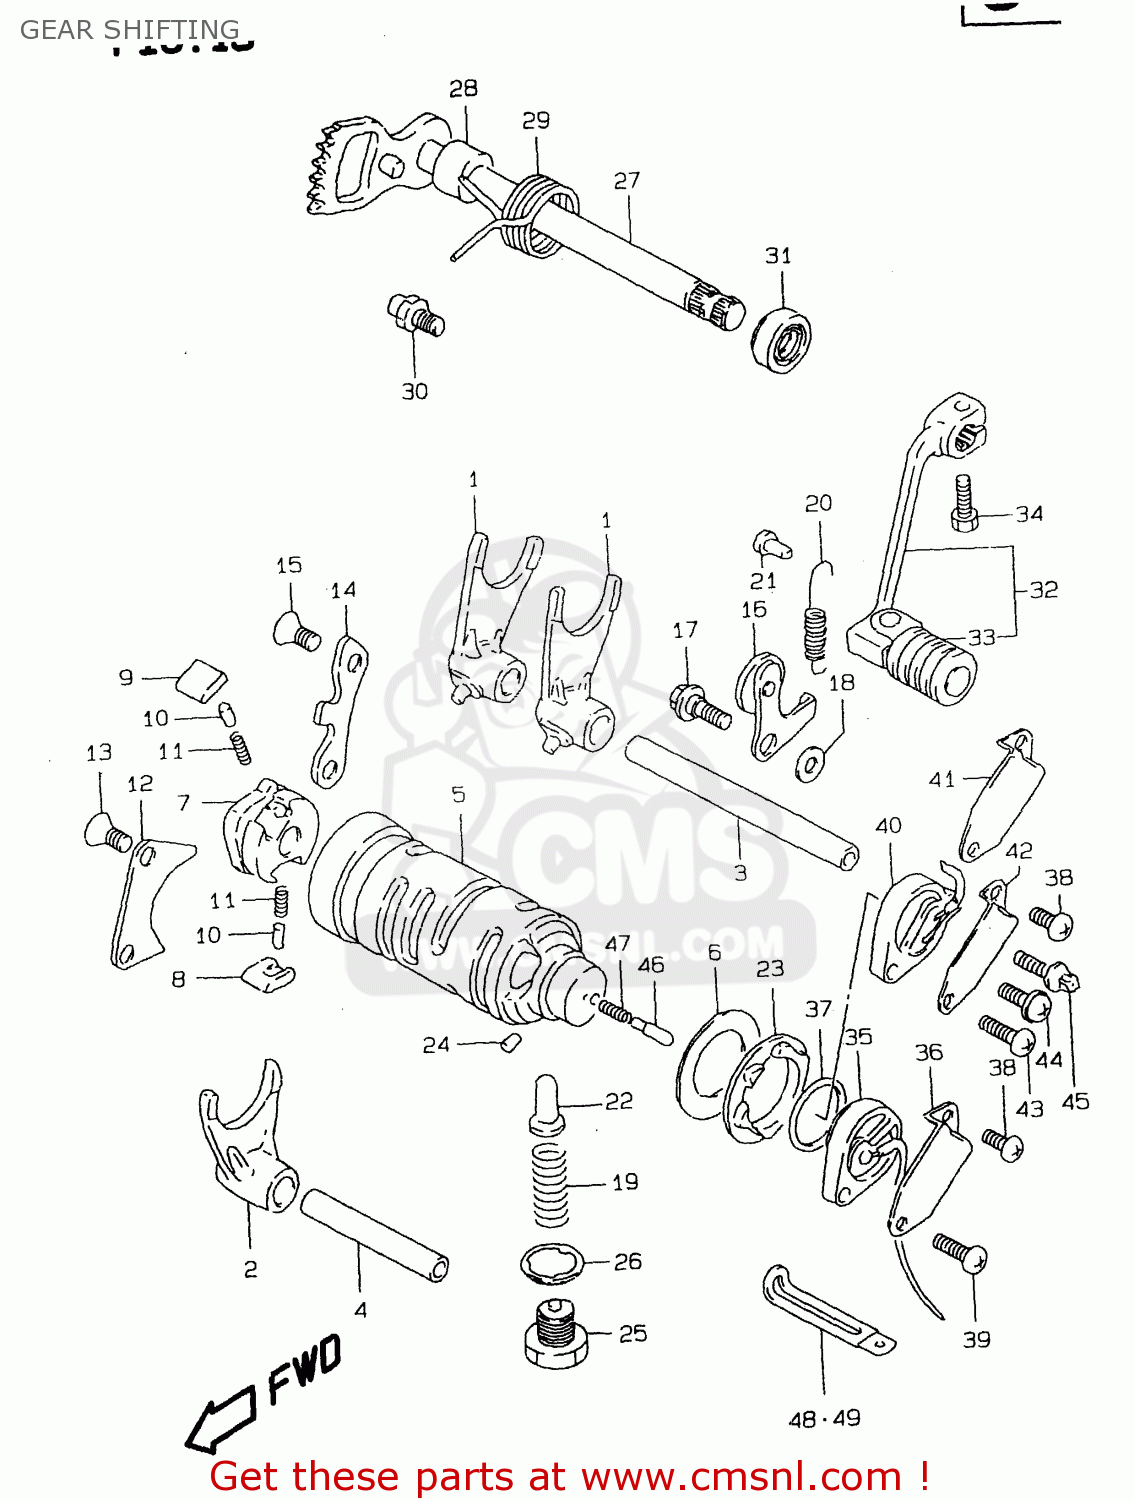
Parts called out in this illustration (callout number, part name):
1	FORK,GEAR SHIFT NO.2
2	FORK,GEAR SHIFT NO.3
3	SHAFT,GEAR SHIFT FORK(L:109)
4	SHAFT,GEAR SHIFT FORK
5	CAM,GEAR SHIFT
6	WASHER,THRUST
7	GEAR,GEARSHIFT CAM DRIVE
8	PAWL,GEAR SHIFT NO.1
9	PAWL,GEAR SHIFT NO.2
10	PIN(5X8)
11	SPRING
12	LIFTER,GEAR SHIFT POLE
13	SCREW
14	GUIDE,GEAR SHIFT CAM
15	SCREW
16	STOPPER,GEAR SHIFT CAM
17	BOLT
18	WASHER
19	SPRING
20	SPRING
21	RIVET
22	STOPPER,GEAR SHIFT CAM NO.2
23	PLATE,GEAR SHIFT CAM STOPPER
24	PIN
25	PLUG(14X12)
26	GASKET(14X19.2X2) (NAS)
27	SHAFT,GEAR SHIFT
28	SPACER(12X20X15.3)
29	SPRING
30	STOPPER,GEAR SHIFT CAM
31	OIL SEAL
32	LEVER ASSY,GEAR SHIFT
33	RUBBER,GEAR SHIFT PEDAL
34	BOLT
35	BASE ASSY,NEUTRAL SW TERMINAL
36	PROTECTOR,GEAR SHIFT SW
37	O RING(D:2.4,ID:21.8)
38	SCREW
39	SCREW
40	BASE ASSY,GEAR SHIFT TERMINAL
41	PROTECTOR,GEAR SHIFT SW
42	PROTECTOR,NEUTRAL SW
43	SCREW
44	SCREW 5X20
45	BOLT
46	PIN(5X15.5)
47	SPRING
48	CLAMP(L:65)
49	CLAMP(L:65)
